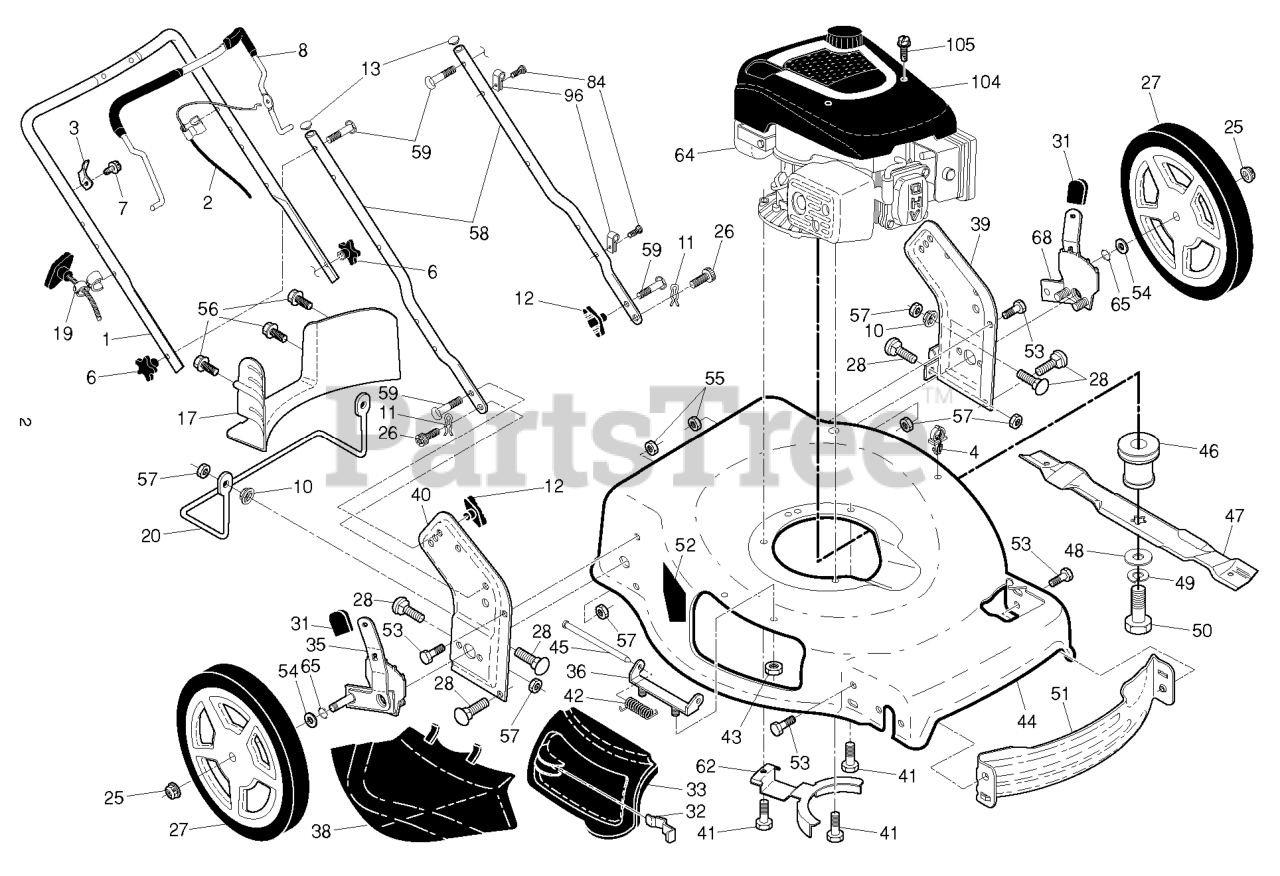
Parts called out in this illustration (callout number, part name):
1	HANDLE.UP.CURVED.PUSH/SSDR.BLA
2	CABLE.MZR.FGD.22+.ERGO
3	BRACKET.UPSTOP.RT
6	KNOB.HANDLE.PLASTIC.STAR.BLACK
8	BAIL.OVER.MOLD.ERGO.MZR.YELLOW
10	WASHER 5/16"
11	COTTER.HAIRPIN.DOOR/HANDLE.PIV
12	KNOB, DEFLECTOR
13	PLUG.PLASTIC.7/8".14-20.GAUGE
17	BAFFLE.22PLUS.FGD.REAR.
19	RB GUIDE.ROPE.STD.BLK.ZIN WSL
20	FOOTGUARD.REAR.22PLUS.BLK
25	NUT.HEX.FLANGE.3/8-16.LOCKNUT
26	SCREW,DOOR/HANDLE.PIVOT
27	WHEEL.12 X 1.75.5SPK.RAD3.YELL
28	BOLT
32	LATCH.DOOR.ZINC
33	DOOR.MULCH.22.BLACK.MULTI-BRAN
35	ADJUSTER.ASM.9POS.HW.R/R
36	BRACKET.ASM.HINGE.21.FWGD.
38	DEFLECTOR.CLIPPING.22.BLACK
39	BRACKET.ASM.HANDLE.LT.22+.FG
40	BRACKET.ASM.HANDLE.RT.22+.FG
41	BOLT 3/8-16X1-1/8
42	SPRING.TORSION
43	NUT.HEX.FLANGE.1/4
44	KIT.HSG.22+SIDE.FGD.428.CE.13
45	ROD.HINGE.21
46	ADPTER.BLAD.25M.VS.22PLU.STAR
47	BLADE.22+4N1.2PIN.5STAR.(P07)
48	WASHER,HARDEN
49	LOCKWASHER
50	SCREW, HEX HD 3/8-24 X 1-3/8
51	BAFFLE.FRONT.22.PLUS
52	DECAL.INTERNATIONL.CUTFINGER
53	BOLT.5/16HEX.WHS.HD
54	WASHER.FLAT.1/2
55	NUT.HEX.FLANGE.1/4
56	SCREW.HX.13X.750
57	LOCKNUT-FLANGE 5/16-18
58	HANDLE.LOWER.22+BT.2PC.BLK
59	BOLT, HANDLE 5/16-18X1.75
62	BRACKET.ENG/BELTKEEPER
64	ENGINE RATO.170CC.25M.1-6.AUTO
65	O-RING..070X.487.NEOPRENE
68	ADJUSTER.ASM.9POS.HW.R/L
84	FASTENER.PUSH.O.250X0.783
96	CLIP.CABLE.BLK
104	SHROUD.ENG.RATO.MCCUL.140/170
105	SCREW.SHROUD.RATO.140/170
